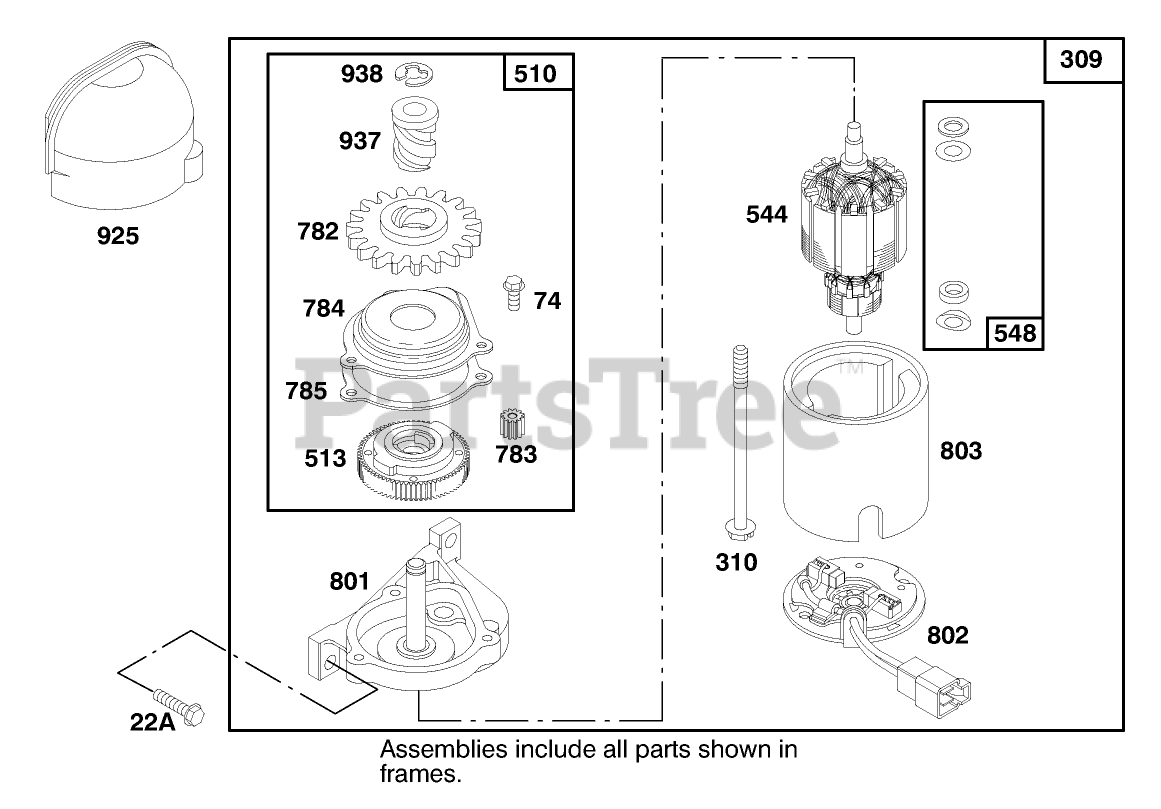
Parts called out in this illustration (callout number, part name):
22A	SCREW - CARBUERTOR MTG
510	DRIVE SET
513	CLUTCH - STARTER
548	WASHER ASSEMBLY
782	GEAR - STARTER
925	COVER - STARTER
938	RETAINER - LOCK
